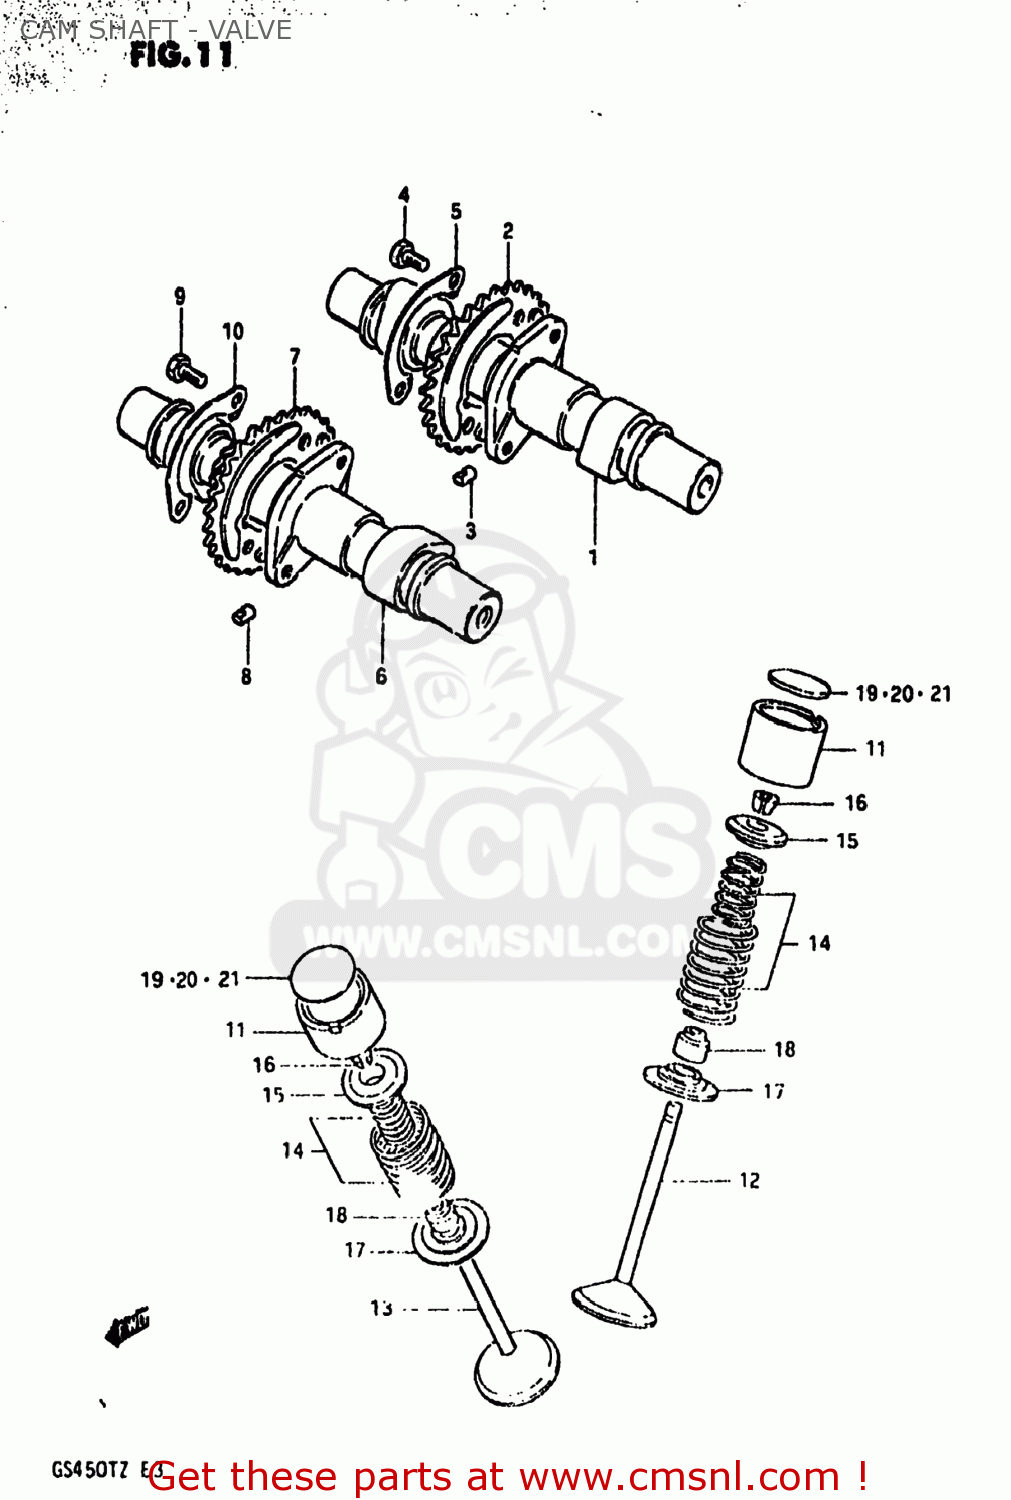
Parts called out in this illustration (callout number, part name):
1	CAMSHAFT,INTAKE
2	SPROCKET,CAMSHAFT
3	PIN,SPROCKET
4	BOLT(6X12.5)
5	WASHER,CAM CHAIN SPROCKET
6	CAMSHAFT,EXHAUST
7	SPROCKET,EXHAUST CAM(NT:30)
8	PIN,SPROCKET
9	BOLT(6X12.5)
10	WASHER,CAM CHAIN SPROCKET
11	TAPPET
12	VALVE,INTAKE
13	VALVE,EXHAUST
14	SHIM,TAPPET
15	RETAINER,VALVE SPRING
16	COTTER VALVE
17	SEAT,VALVE SPRING
18	SEAL,OIL(7X14.4X9)
19	SHIM,TAPPET
20	SHIM,TAPPET
21	SHIM,TAPPET
22	SHIM SET,TAPPET
23	CASE
